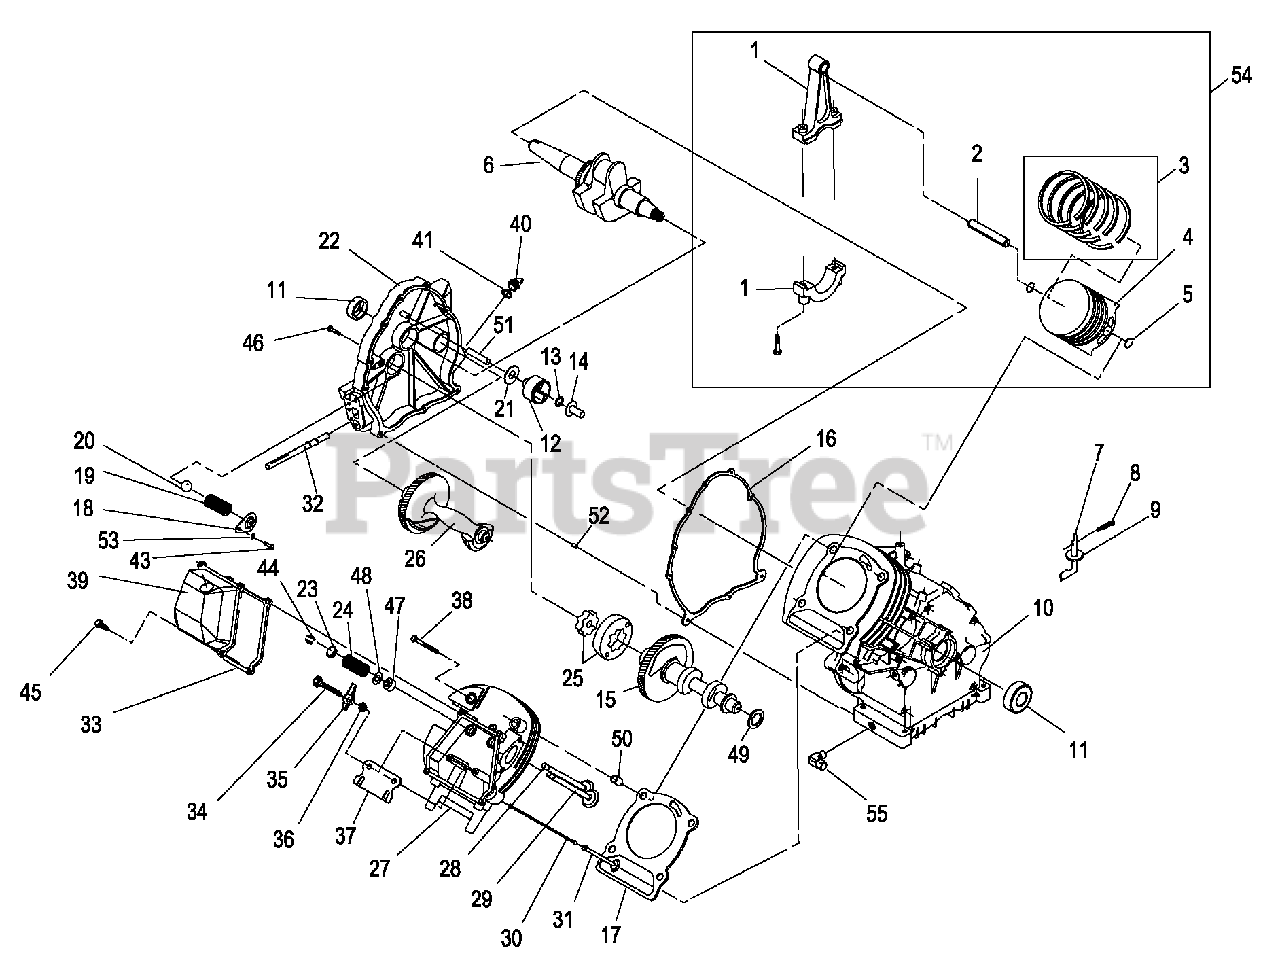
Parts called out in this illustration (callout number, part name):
1	ASSEMBLY, CONNECTING ROD
2	PIN, PISTON D20
3	RING SET, PISTON DIA90
4	PISTON, FLAT TOP DIA90 COATED
5	RETAINE R, PISTON PIN 20
6	ASSEMBLY, CRANKSHAFT GH4 10 SMALLTAPER
7	ARM, G OVERNO RRC4 5
8	PIN COTTER "R" .05 9 X 1 /4 X 1 -1 /8
9	WASHER, GOVERNOR ARM THRUST
10	CRANKCASE, SUBASSEMBLY WITH PLUGS GH4 10
11	SEAL, 3 5 I.D. CRANKSHAFT
12	ASSEMBLY, GOVERNOR GEAR
13	C-RING, GOVERNOR GEAR RETAINER
14	SPOOL, GOVERNOR- MACHINE
15	ASSEMBLY, CAMSHAFT & GEAR
16	GASKET , CRANKCASE
17	GASKET, HEAD 410
18	COVER, OIL PRESSURE RELIEF
19	SPRING, OIL RELIEF 360
20	BALL, DIA 11 /32 PRESSURE RELIEF
21	WASHER, THRUST GOVERNORGEAR
22	ASSEMBLY, COVER, GEAR TOP CHECK / FILL
23	RETAINE R, VALVE SPRING
24	VALVE SPRINGLF
25	SET,GEROTOR 12 THK
26	BALANCER
27	ASSEMBLY,CYLINDER HEAD SEATS & GUIDES
28	VALVE , EXHAUST
29	VALVE , INTAKE
30	PUSH ROD 1 74 .9
31	TAPPET
32	ASSEMBLY, SCREEN OIL PICK-UP
33	GASKET, ROCKER COVER 410
34	STUD, D20 PIVOT BALL
35	ROCKER ARM
36	NUT, JAM (ROCKER ARM)
37	PLATE, PUSH ROD GUIDE
38	SCREW, HHFL M10- 1.5 X 105
39	ASSEMBLY, ROCKER COVER BREATHER OHVI
40	PLUG, OIL FILL PLASTIC, ORANGE
41	O-RING 1 7 .8 I.D. x 2 .4
42	SCREW HHC M5 – 0 .8 X 10 C8 .8
43	KEEPER, V ALVE SPRING
44	SCREW HHFCS M6 -1 X 12
45	SCREW, HHFC M8 -1.2 5 X 4 2
46	SEAL, VALVE S TEM D7
47	WASHER, VALV E SPRING
48	WASHER, LARGE SPRING
49	SLEEVE , DOWEL PIN 14 DIA.
50	SHAFT, GOV ERNOR RC5 5
51	SLEEVE , DOWEL PIN 12 DIA.
52	WASHER LOCK M5 RIBBE D
53	ASSY PISTON P IN/CONNECTING ROD HC GH4 10
54	DRAIN FITTING ASS Y-XP PORTABLE
